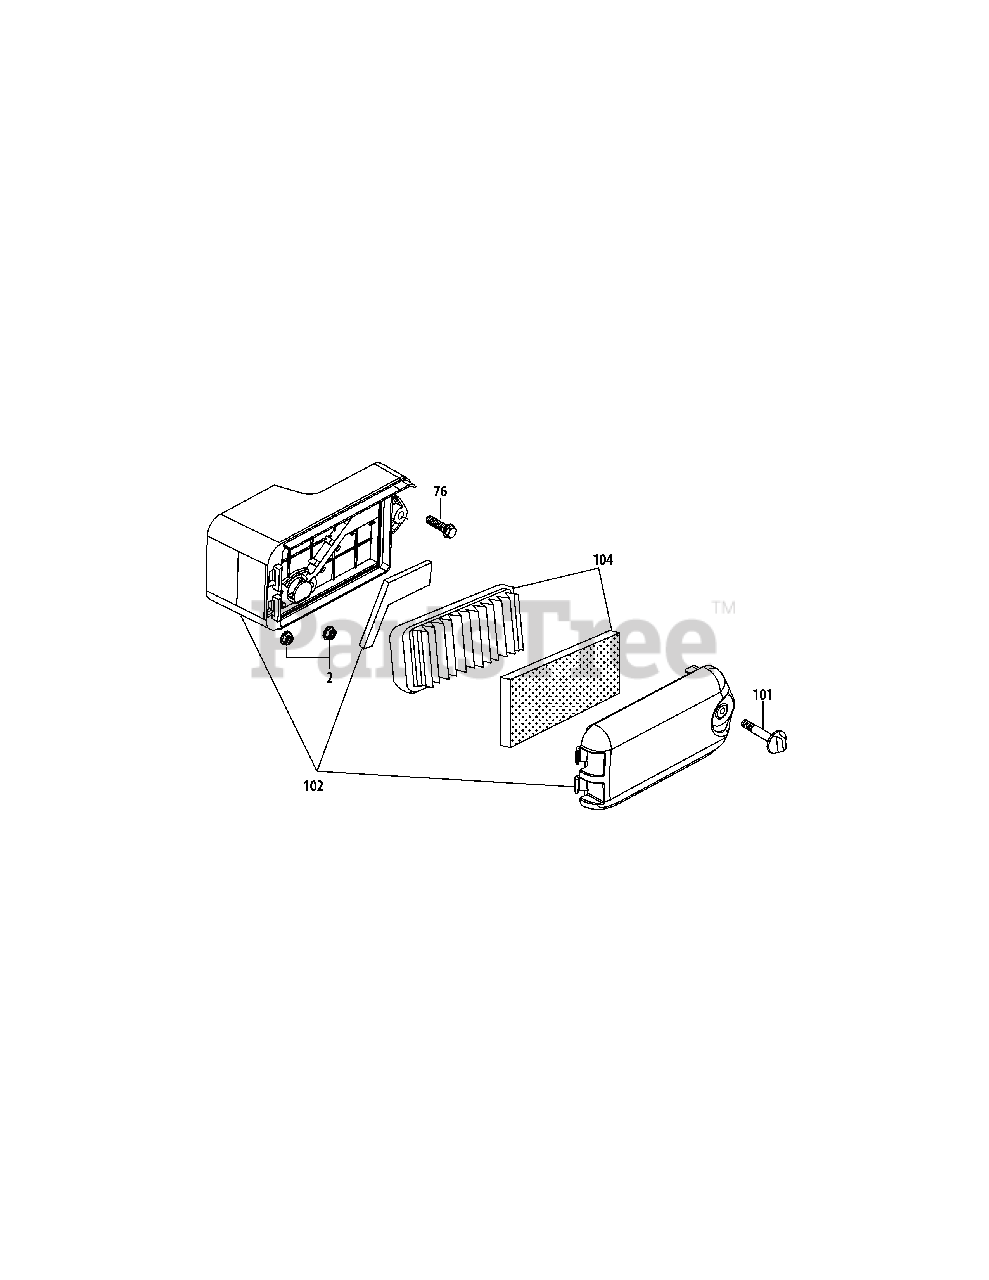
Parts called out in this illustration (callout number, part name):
2	Nut M6X10Mm Starter/Carb/Muffler
76	Bolt M6X35 Af Base/Brake/Dipstick
101	Air Filter Cover Thumb Screw
102	Air Cleaner Housing Ass'y Comp
104	Air Cleaner Kit
